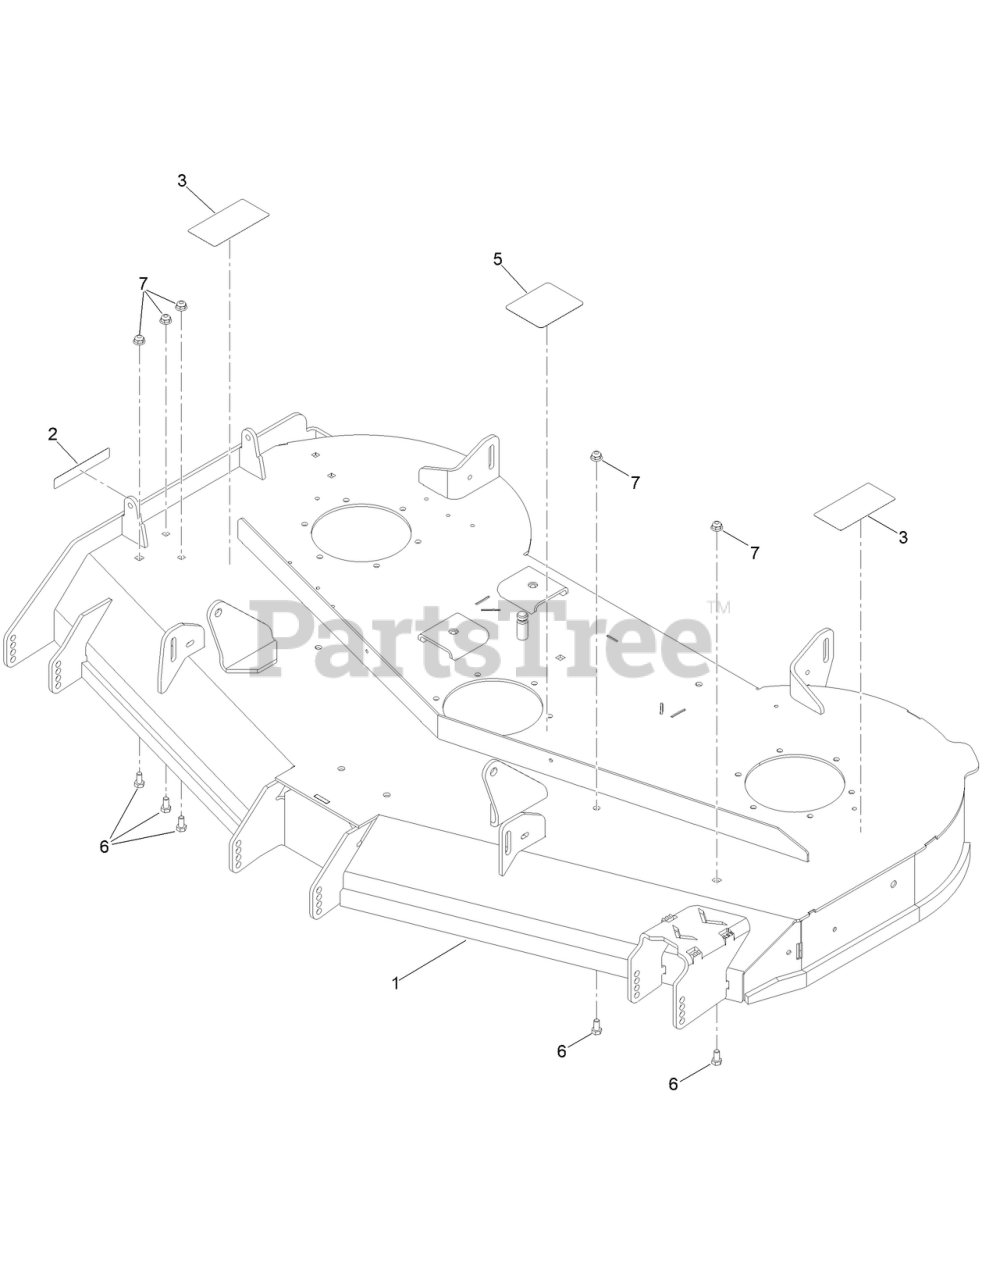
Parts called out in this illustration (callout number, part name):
2	DECAL-DANGER
3	DECAL-DANGER, DECK
5	DECAL-BELT ROUTING
6	SCREW-HH
7	NUT-HF
